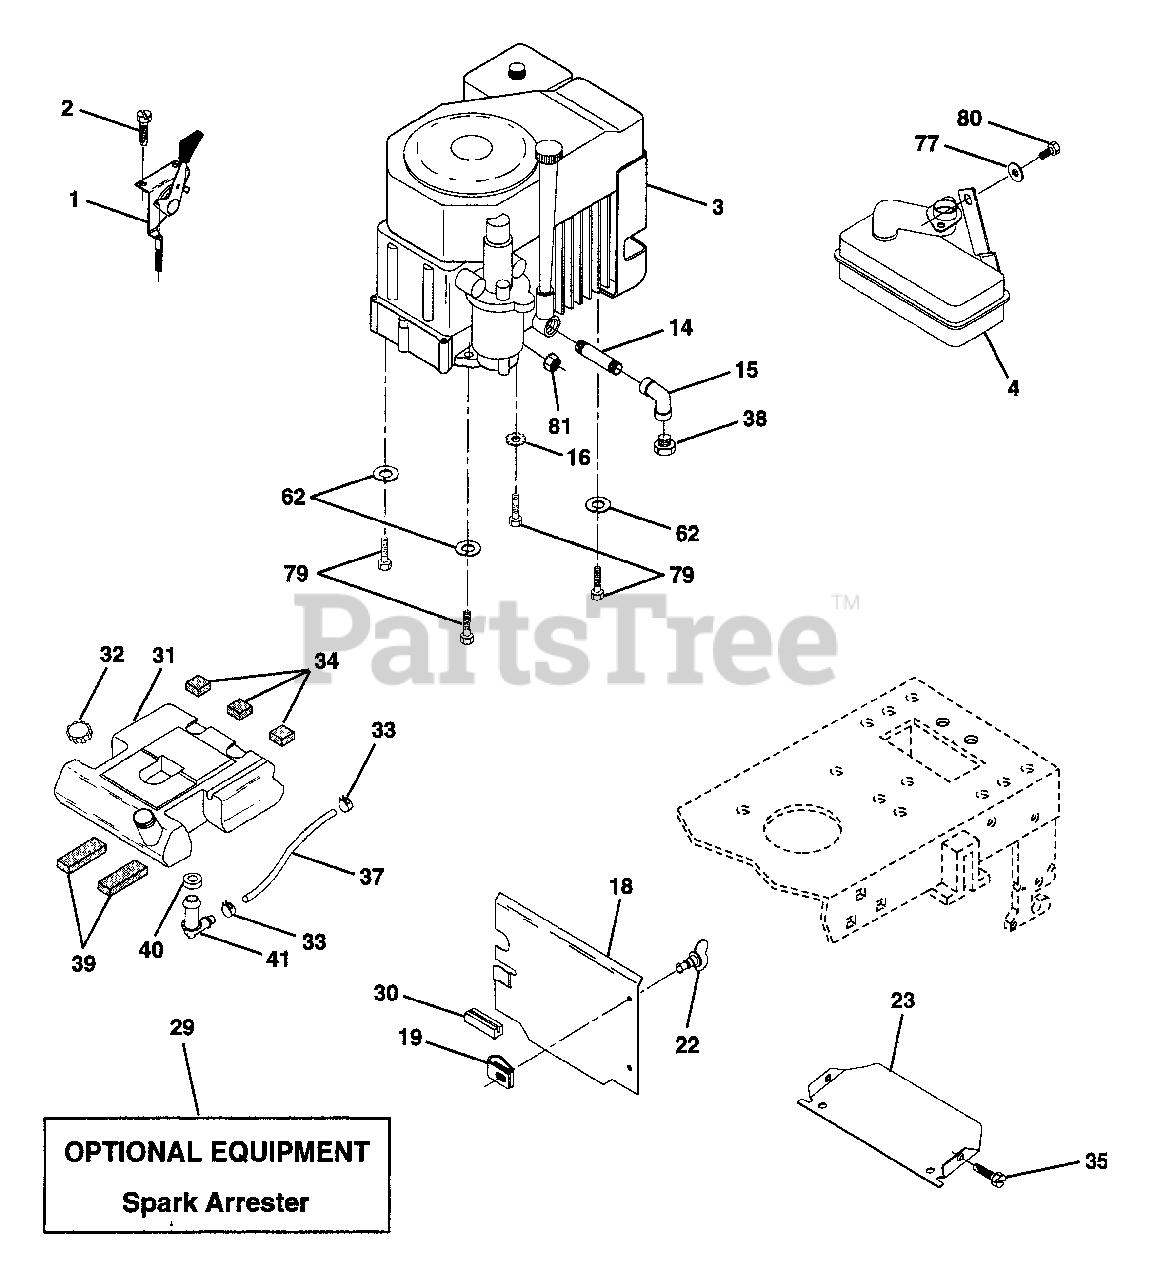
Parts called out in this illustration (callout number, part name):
1	Control THTICH 27 LH FIAG DOM
2	Screw Hex Thd Cut 1/4-20x5/8 T
3	Engine Kohler, Model Number CV15S 15 HP
4	Muffler LT Koh 12.5/15HD
14	Nipple Pipe 3/8 Npt X 3-1/2
15	Elbow Std 90 Degree 3/8-18 Npt
16	Washer Lock Ext Tooth 5/16
18	Shield Heat Lt
19	Receptacle 1/4 turn
22	Stud 1/4 turn w/Bushing Plst.
23	Shield Browning
29	Kit Spark Arrestor (Flat Scrn)
30	Pinch Weld Hood Black
31	Tank Fuel Rear 3.50 YT/GT
32	Cap Asm Fuel W/sym Vented
33	Clamp Hose Black
34	Pad, Spacer 1 x 1 x 1 Blk
35	Screw Thdrol 5/16-18 x 3/4 Tyt
37	Line Fuel 7.5"
38	Plug Oil Drain
39	Pad, Idler 1.75 x .75 x .06
40	Bushing
41	Stem, Tank, Fuel
62	Washer Lock Hvy Hlcl Spr. 5/16
77	Washer 5/16 x 3/4 x 16 Ga.
79	Bolt Hex
80	Bolt Hex Hd 5/16-18 UNC x 1/2
81	Nut Flange 1/4-20 Starter Nut
